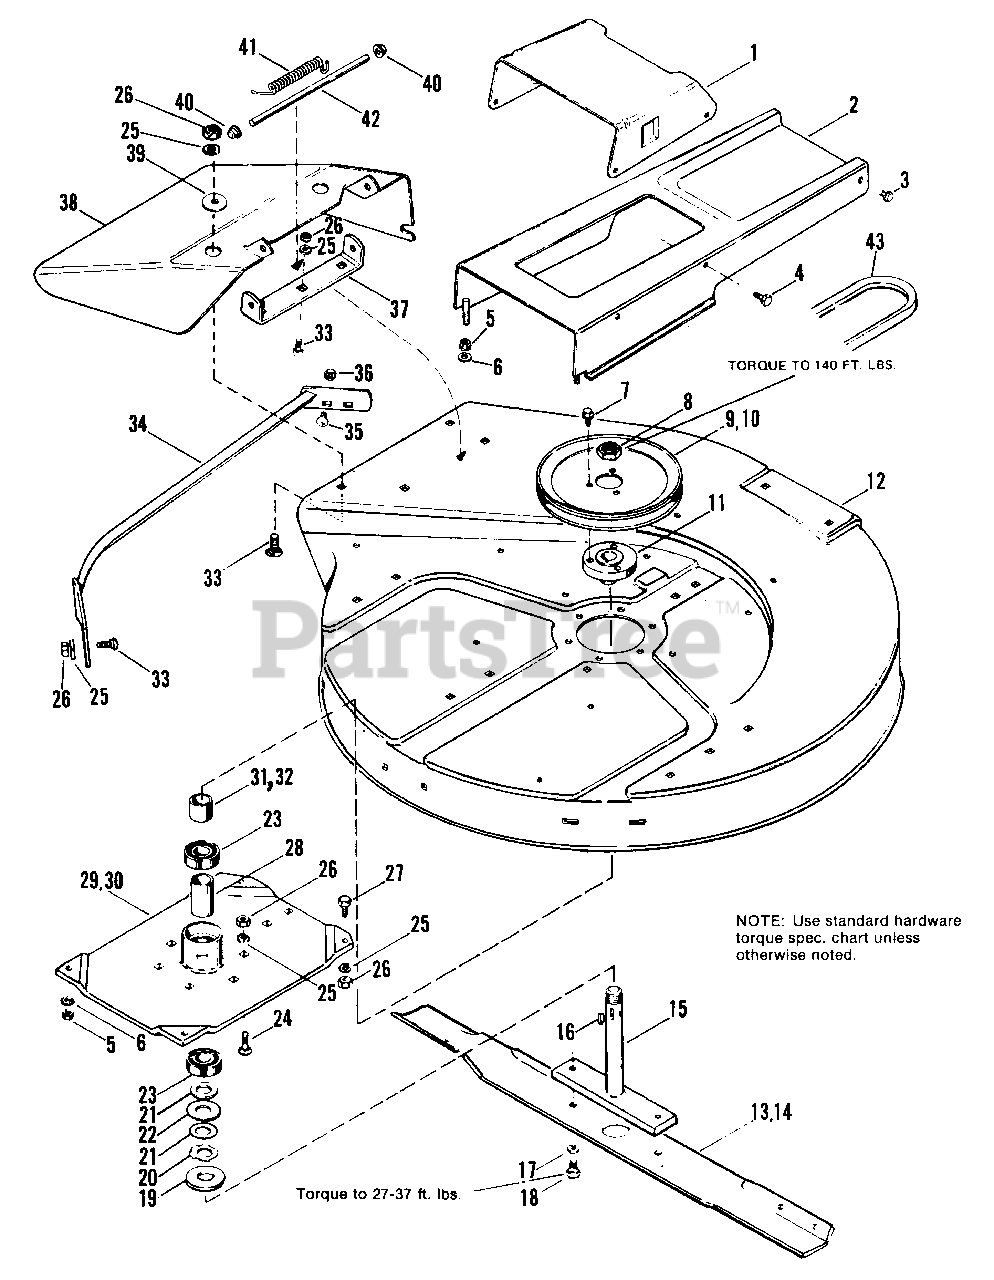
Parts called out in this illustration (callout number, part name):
1	COVER, Upper
2	COVER ASSY., Lower
3	CAPSCREW, Hex Hd., 3/8-16 x 1/2
4	SCREW, Taptite, 1/4-20 x 3/8
5	LOCKNUT, Hex, 5/16-18
6	WASHER, Plain, 5/16
7	SCREW, Thd. Forming, 3/8-16 x 3/4
8	LOCKNUT, Jam, 3/4-16
9	PULLEY
10	PULLEY
11	HUB, Pulley
12	HOUSING, Mower, 30"
13	BLADE, 30"
14	BLADE, 30"
15	ARBOR ASSY.
16	KEY, Woodruff, #61
17	LOCKWASHER, 3/8
18	CAPSCREW, Hex Hd., 3/8-16 x 7/8
23	BEARING, Ball
24	BOLT, Carriage, 5/16-18 x 1
25	LOCKWASHER, 5/16
26	NUT, Hex, Full, 5/16-18
27	CAPSCREW, Hex Hd., 5/16-18 x 1
29	TUBE ASSY., Arbor
30	TUBE ASSY., Arbor
31	SPACER
32	SPACER
33	BOLT, Carriage, 5/16-18 x 3/4
34	GUARD ASSY., Stone
35	BOLT, Carriage, 5/16-18 x 1/2
36	LOCKNUT, Jam, 5/16-18
37	SUPPORT, Hinge
38	DEFLECTOR
39	WASHER
42	PIN, Hinge
43	V-BELT, 49.1"
